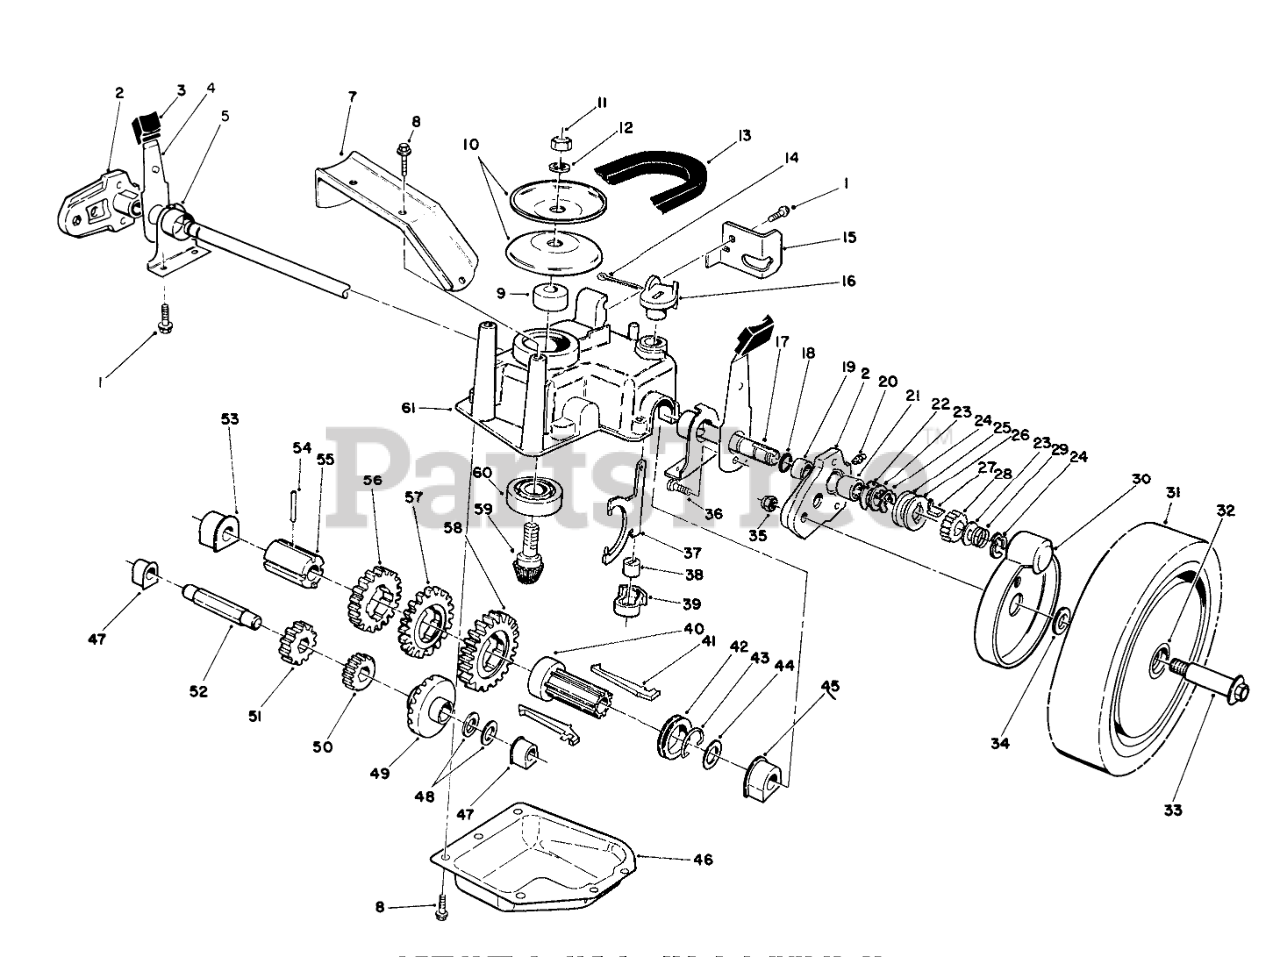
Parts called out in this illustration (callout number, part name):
1	SCREW-HWHTF
2	Pivot Arm Assembly (Incl . Ref . #19-21)
3	KNOB-ARM
4	SPRING ARM ASM
5	CAP-END
7	Bracket-BeltGuide
8	SCREW-HWHTF
9	SPACER
10	Pulley Half
11	NUT-HEX
12	WASHER-FLAT
13	V-BELT
14	PIN-COTTER
15	RETAINER-CABLE
16	LEVER-SHIFT
17	SHAFT-OUTPUT
18	O-RING
19	BUSHING
20	FITTING-GREASE
21	BEARING-ROLLER
22	WASHER-ARM, PIVOT
23	WASHER-THRUST, KEYED
24	RING-CLIP, LOCKING
25	RING-FRICTION
26	WASHER-CLUTCH
27	KEY-ROCKING, LH
28	GEAR-PINION
29	SPRING-COMPRESSION
30	COVER-WHEEL
31	Wheel Tire & Gear Assy. (Incl. Ref. #32)
32	BUSHING
33	WHEEL BOLT
34	SPACER-COVER, WHEEL
35	NUT-LOCK
36	SCREW-HSH, THREAD FORMING
37	YOKE-SHIFT
38	BUSHING-YOKE
39	RETAINER-FORK, SHIFT
40	SLEEVE-KEY, SHIFT
41	KEY-SHIFT
42	COLLAR-SHIFT
43	CLIP-SPRING
44	WASHER-PLAIN
45	BUSHING-OUTPUT
46	Cover-Gearcase
47	BUSHING
48	WASHER-THRUST
49	Gear-Bevel
50	PINION-20T
51	PINION-25T
52	SHAFT-INTERMEDIATE
53	BUSHING
54	PIN-SPRING
55	SLEEVE-GEAR
56	GEAR-39T
57	GEAR-44T
58	GEAR-49T
59	Gear-Pinion
60	BEARING-BALL
61	CASE-GEAR, UPPER
